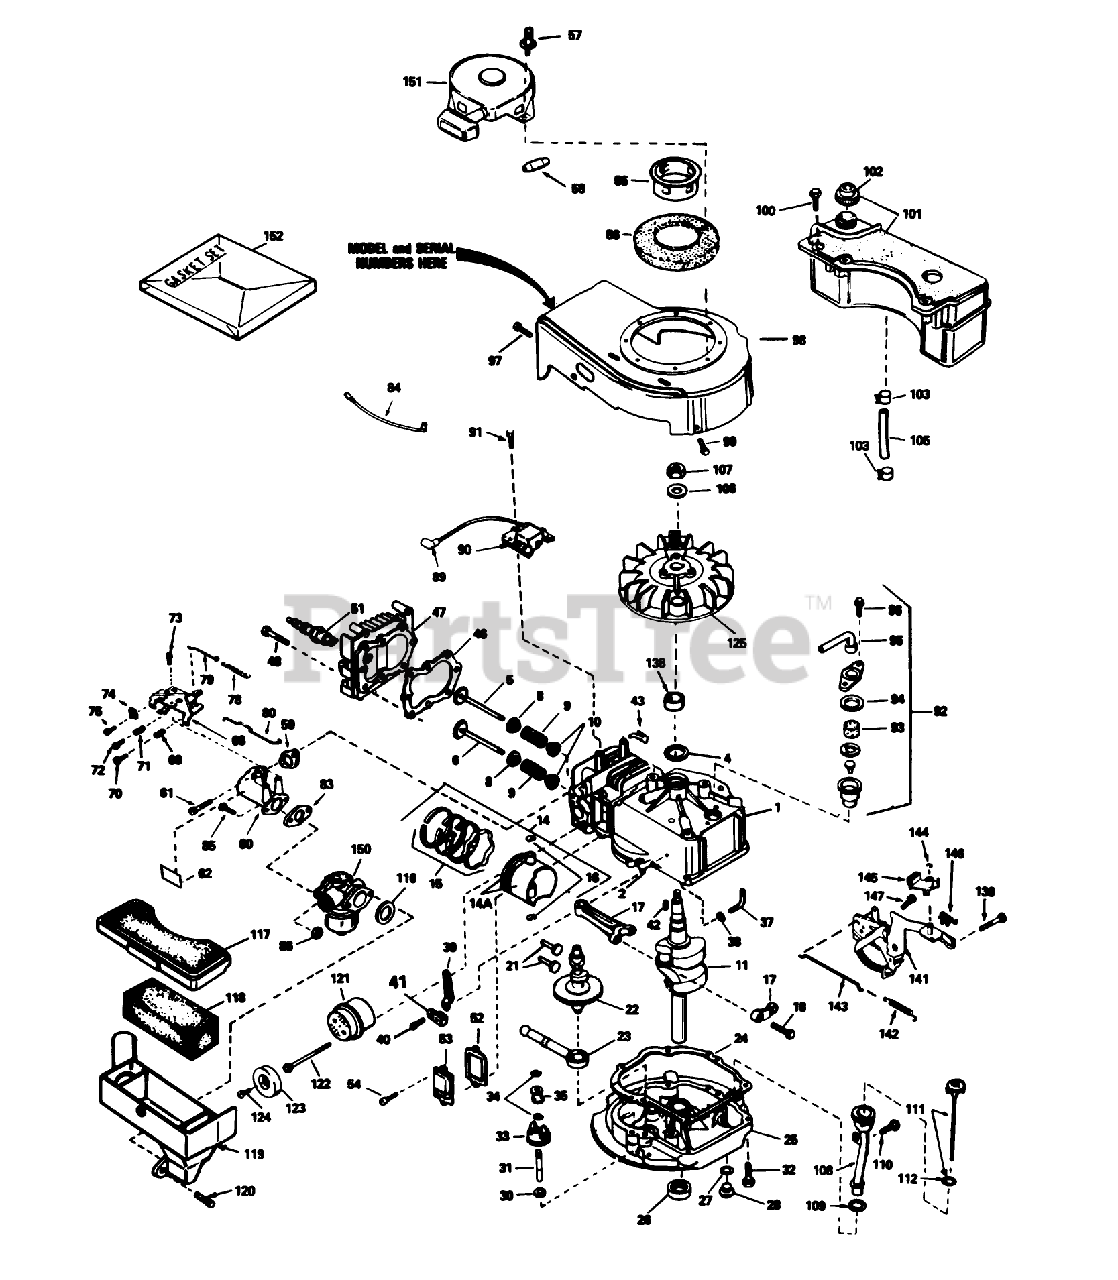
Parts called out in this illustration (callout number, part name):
1	Cylinder Assembly (Incl. Ref. #2, 4, 94 96)
2	Pin-Dowel
4	Seal-Oil
5	Valve, Intake (Std.) (Incl. Ref. #40)
5	Valve, Intake (1/32" oversize)(Incl. No. 40)
6	Valve, Exhaust (Std.)(Incl. No. 40)
6	Valve, Intake (1/32" oversize)(Incl. No. 40)
8	Cap-Upper Valve Spring
9	Spring-Valve
10	Cap-Valve, Spring
11	Crankshaft
14	Piston-Pin Ring Assy. (Std.)(Incl. Ref. #14A, 15 16)
14	Piston-Pin Ring Assy. (.010 oversize)(Incl. Ref. #14A, 15 16)
14	Piston-Pin Ring Assy. (.020 oversize)(Incl. Ref. #14A, 15 16)
14A	Piston Pin Assy. (Std)(Incl. Ref. #16)
14A	Piston Pin Assy. (.010 oversize) (Incl. Ref. #16)
14A	Piston Pin Assy. (.020 oversize) (Incl. Ref. #16)
15	Piston Ring Set Std.
15	Piston Ring Set .010 O.S.
15	Piston Ring Set .020 O.S.
16	Ring-Retaining, Piston Pin
17	Rod Assy., Connecting (Incl. Ref. #17)
18	Screw-Connecting Rod
21	Lifter-Valve
22	Camshaft(Mech.Comp. Release)
23	Oil Pump ASM
24	Gasket, Mounting
25	Flange Assy.-Mounting (Incl. Ref. #26, 27, 28 31)
26	Seal Oil
27	Gasket-Oil Drain
28	Plug Oil Drain
30	Washer-Flat
31	Shaft-Governor
32	Screw (1/4-20 x 1-1/4)
33	Governor Gear ASM
34	Ring-Retaining
35	Spool-Governor
37	Rod, Governor (Incl. No. 36)
38	Washer-Flat
39	Governor Lever
40	Screw
41	Clamp-Lever, Governor
42	Key-Flywheel
43	Clip-Wire
46	Gasket-Cylinder Head
47	2025A67 ADD.ASSEMBL
48	Screw (5/16-18x1-1/2)
51	Plug, Spark (Autolite 458, Champion J-19LM or equiv.)
52	Gasket-Breather
53	Cover-Valve
54	Screw
55	Cup-Starter
56	Screen-Starter
57	Pop Rivet (Can be purchased locally)
58	Retainer-Starter Rope
59	Gasket-Intake
60	Pipe-Intake (Incl. Ref. #59)
61	Screw (1/4-20 x 1)
62	Decal-Primer
68	Control Assy.-Remote Speed (Incl. Ref. #69 thru 72 76)
69	61709/GIL1515A/95-5
70	Screw
71	Spring-Compression
72	Screw
73	Screw (10-24 x 9/16)
74	Conduit
75	Screw (10-32 x 3/8)
78	Spring Governor
79	2035A67 ADD.ASSEMBL
80	Link-Throttle
83	Gasket
84	Ground Wire
86	Nut and Lock Washer (1/4-28)
89	Cover-Spark Plug
90	Solid State
91	Screw
92	Breather Assy. (Incl. Ref. #46 thru 51)
93	Element-Breather
94	Gasket-Breather
95	Tube, Breaker
96	Screw (10-24 x 9/16)
97	Screw (10-24 x 9/16)
98	Housing-Blower
99	Screw (1/4-20 x 1/2)
100	Screw (10-32 x 35/64)
101	Tank Assembly-Fuel (Incl. Ref. #102)
102	Cap-Fuel
103	Clamp-Line, Fuel
105	Line-Fuel
106	Washer-Belleville
107	Nut-Flywheel
108	Tube-Oil Fill
109	Gasket
110	Screw (10-32 x 1/2)
111	Dipstick-Oil (Incl. Ref. #112)
112	O-Ring
116	Gasket-Cleaner, Air
117	Cover Air Cleaner
118	Filter-Air Cleaner
119	Body Air cleaner
120	Screw
121	Muffler (Incl. Ref. #122)
122	Screw
123	Cover-Muffler
124	Screw
125	Flywheel
138	Spacer
139	Screw (1/4-20 x 3/8)
141	Bracket Assy.
142	Spring-Extension
143	Link-Control
144	Ring-Retaining
145	Lever-Brake
146	Terminal
147	Screw-Hex. Hd.
150	Carburetor (Incl. Ref. #83)
151	tarter-Rewind
152	Gasket Set
